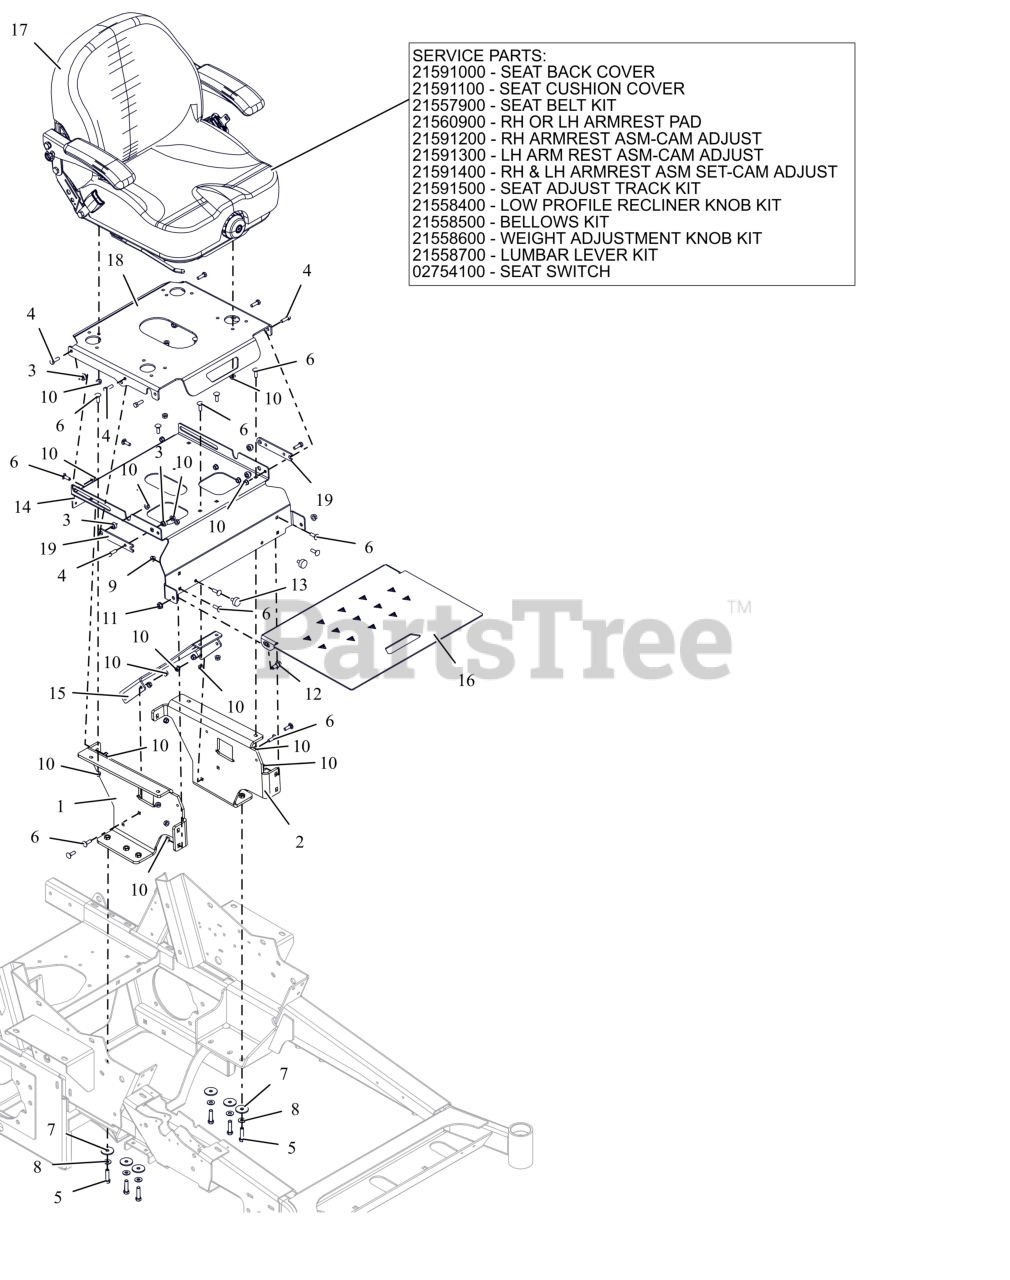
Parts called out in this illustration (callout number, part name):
1	BRKT- SEATBOX RH SUPPORT - RED
2	BRKT- SEATBOX LH SUPPORT
3	SPCR, BRG .315X.500X.481X.281
4	BLT, HEX .31-18X1.00 G8 ZCC
5	BLT, HEX 0.375-16X1.5 GR8 ZCC
6	BLT,RHSN .31-18X1.00 G5 ZCC
7	WSHR, FLT .380X1.50X.125 ZCC
8	WSHR, HDND 0.375X0.875X0.064 ZCC
9	NUT,SPNLK-FLG .31-18 G5 ZCC
10	NUT,LK-CTR-FLG .31-18 GF ZCC
11	NUT-LK-CTR-FLG .375-16 GF ZCC
12	BLT,SHLDR EP .38-16X.30 HEX YZ
13	BUMPER, RUBBER
14	BRKT- SEATBOX ISOLATOR MTG
15	BRACE- CROSS
16	FOOTREST
17	SEAT- FULL SUSPENSION
17	SEAT BACK COVER
17	SEAT CUSHION COVER
17	KIT, SEAT BELT
17	PAD, ARMREST RH OR LH (HARD)
17	RH ARMREST ASM - CAM ADJUST
17	LH ARM REST ASM - CAM ADJUST
17	RH & LH ARMREST ASM SET - CAM ADJUST
17	SETA ADJUST TRACK KIT
17	KIT, LOW PROFILE RECLINER KNOB
17	KIT, BELLOWS
17	KIT, WEIGHT ADJUSTMENT KNOB
17	KIT, LUMBAR LEVER
17	SWITCH- SNAP MTG N.O.
18	BRKT, SEATBOX TILT UP (RED)
19	BRKT- SEATBOX TILT UP PIVOT
